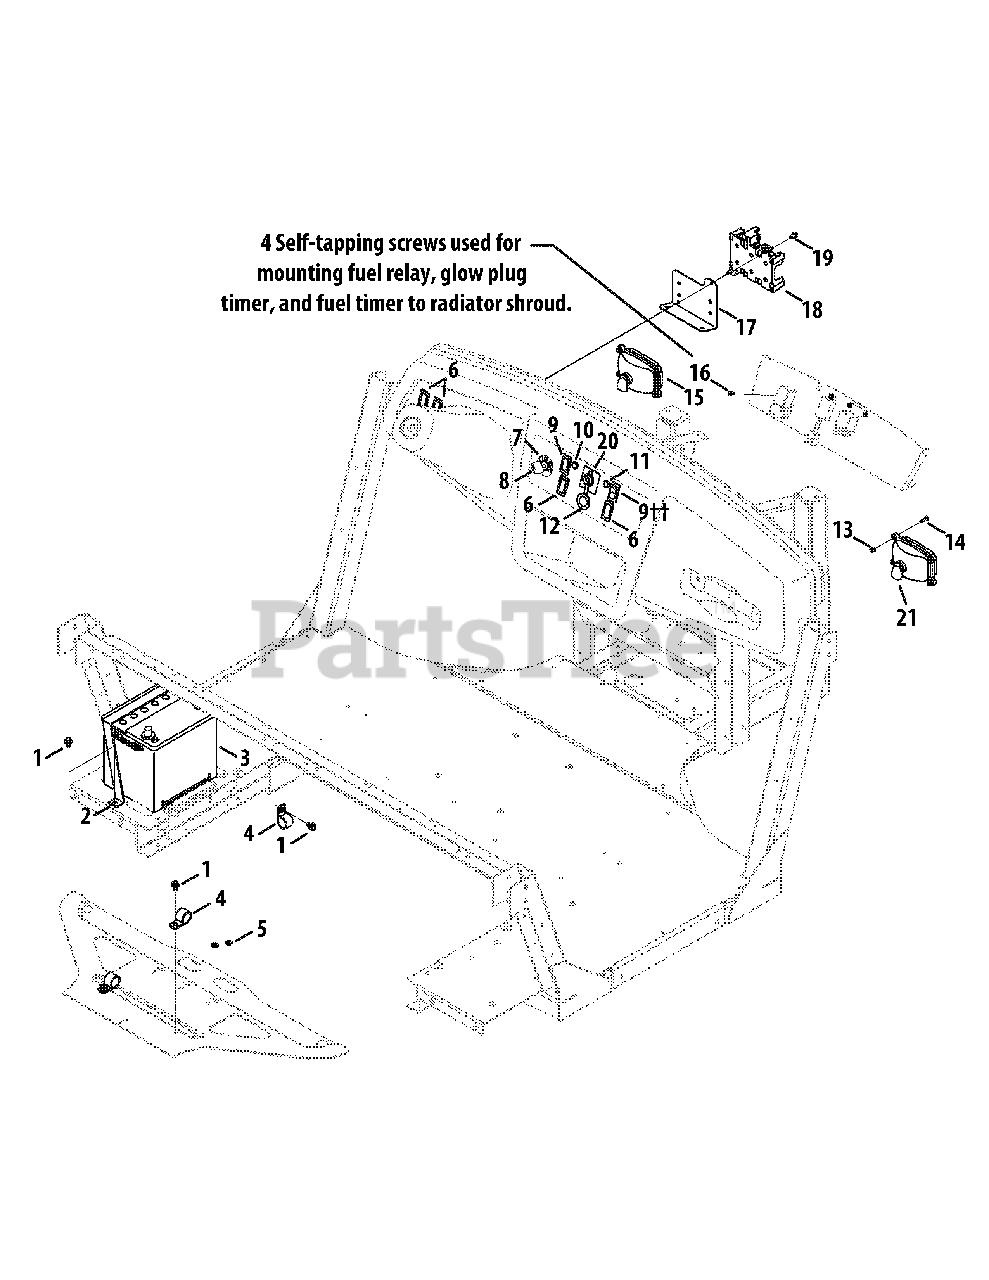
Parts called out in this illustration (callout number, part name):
1	Screw, TT, 5/16-18 x .500
2	Bracket, Mt., Battery
3	Battery, 450 CCA Wet
5	Washer, Lock, 5/16
6	Panel, Plug, Switch
7	Switch, Key, 4 Pos. Delta
8	Key, Delta, Plastic
9	Switch, 4x4, Rocker
10	Light, Ind., Yellow, LED
10	Lamp, Ind., Green, Incandescent
11	Light, Ind., Red, LED
11	Lamp, Ind., Red, Incandescent
12	Receptacle, Power, 12v
13	Nut, Hex Lock, #10-24
14	Screw, TT, #10-24 x .750
15	Headlight Assembly (Incl. # 24)
16	Screw, #10-16 x .500
17	Bracket, Fuse Mount
18	Relay, Holder, 3-Way
19	Screw, TT, 1/4-20 x .500
20	Meter, Ind., Hour Flat Face
21	Head lamp Bulb
